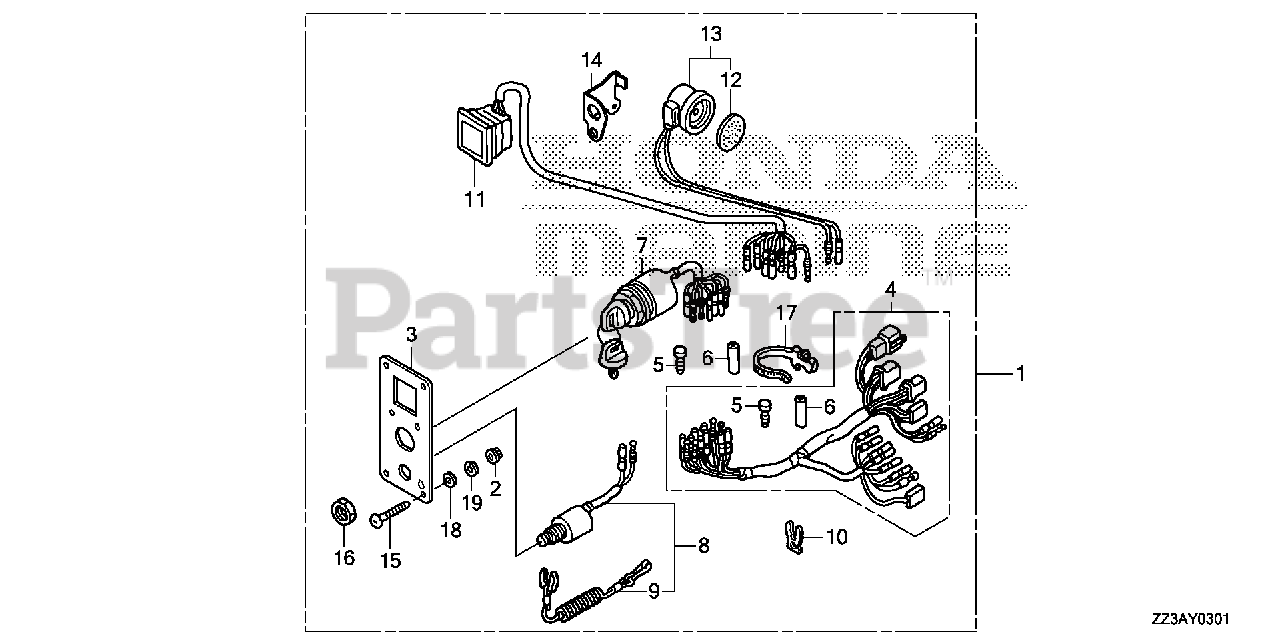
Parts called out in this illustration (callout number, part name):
1	PANEL KIT, SWITCH (4-LED)
2	NUT, FLANGE (5MM)
3	PANEL, CONTROL
4	HARNESS ASSY., SWITCH PANEL
5	PLUG, CONNECTOR (INNER)
6	PLUG, CONNECTOR (OUTER)
7	SWITCH ASSY., COMBINATION
8	SWITCH ASSY., EMERGENCY STOP
9	WIRE, EMERGENCY
10	CLIP, EMERGENCY LOCK
11	LAMP ASSY., INDICATION (4-LED)
12	PLATE, TURN SIGNAL BUZZER
13	BUZZER, WARNING
14	BRACKET, BUZZER
15	SCREW, PAN (5X40)
16	NUT, HEX. (16MM)
17	BAND, WIRE HARNESS (150MM) (NATURAL)
18	WASHER, PLAIN (5MM)
19	WASHER, SPRING (5MM)
